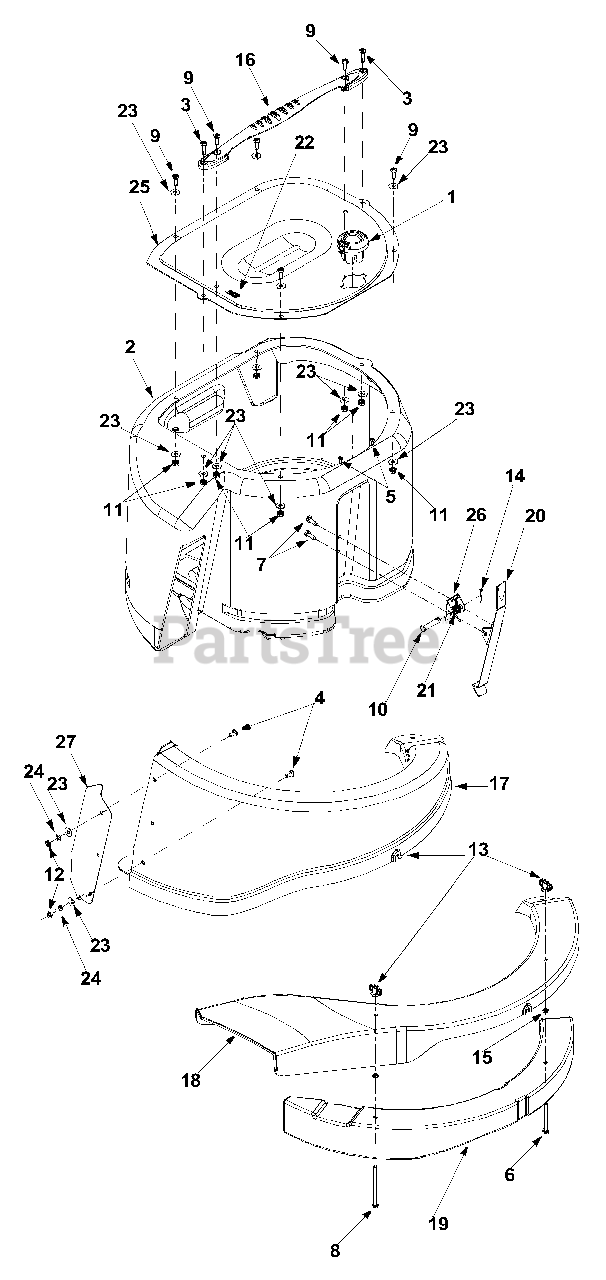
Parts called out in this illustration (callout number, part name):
1	Flow Indicator Assembly
2	Grass Bag Assembly
3	Machine Screw 1/4-20 x 1.0
4	Machine Screw 1/4-20 x 0.5"
5	Hex Screw #10-16 x 0.5"
6	Hex Screw 1/4-20 x 2.75"
7	Self-Tapping Screw 1/4-20 x 0.75"
8	Hex Screw 1/4-20 x 3.75"
9	Machine Screw 1/4-20 x 0.75"
10	Clevis Pin
11	Hex Sems Nut 1/4-20
12	Jam Nut
13	Wing Nut
14	Cotter Pin
15	Speed Nut
16	Bag Handle
17	Discharge Chute: Grass Bag
18	Side-Discharge Chute
19	Mulching Plug
20	Bag Release Lever
21	Torsion Spring
22	Clip Spring
23	Flat Washer
24	Lock Washer
